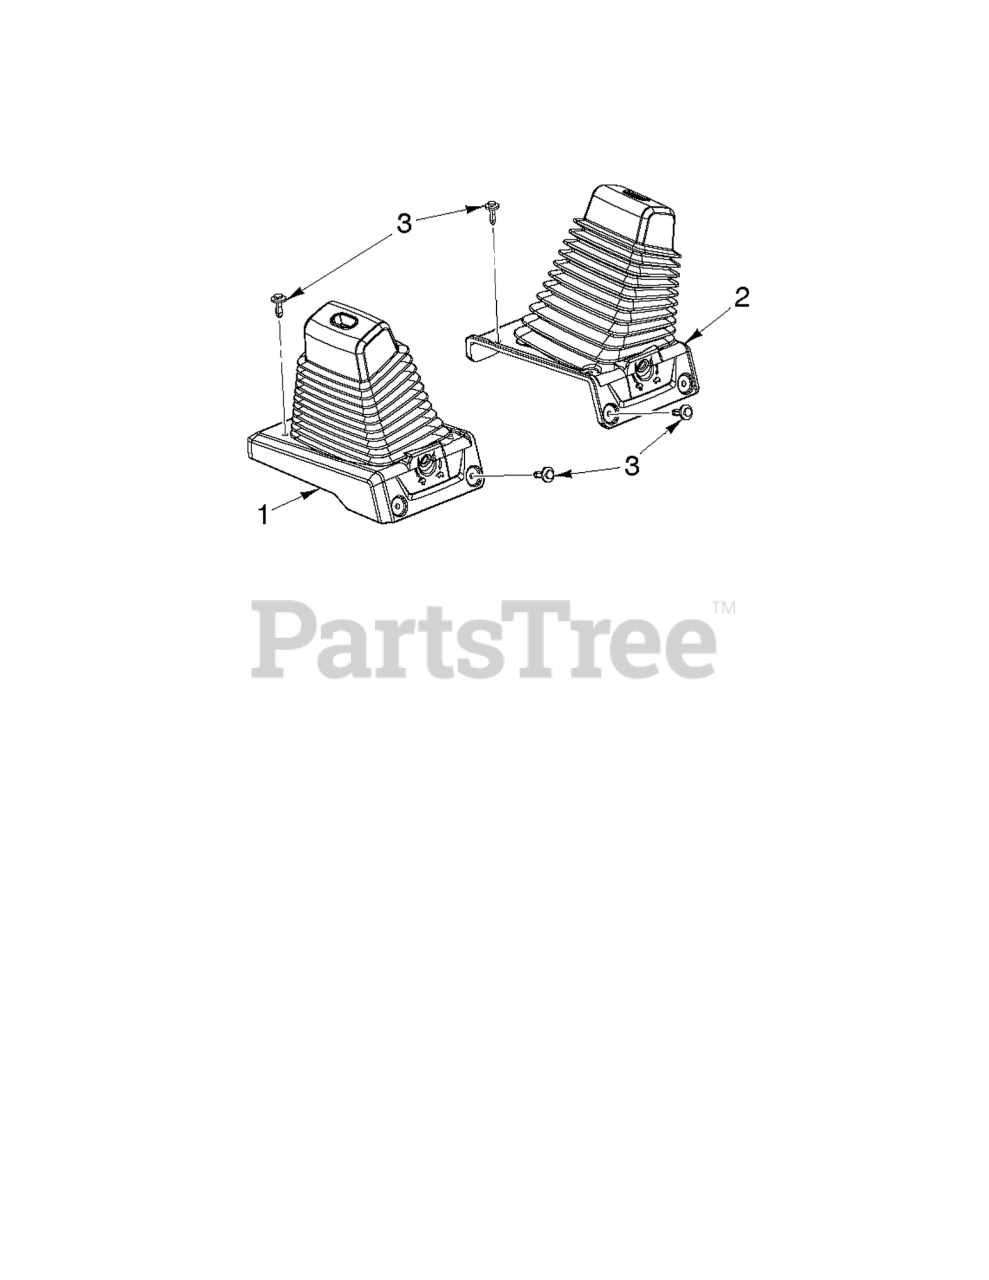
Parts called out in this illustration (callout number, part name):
1	Bellows
2	Bellows
3	RIVET.PUSH.PIN.0.25IN.HOLE
